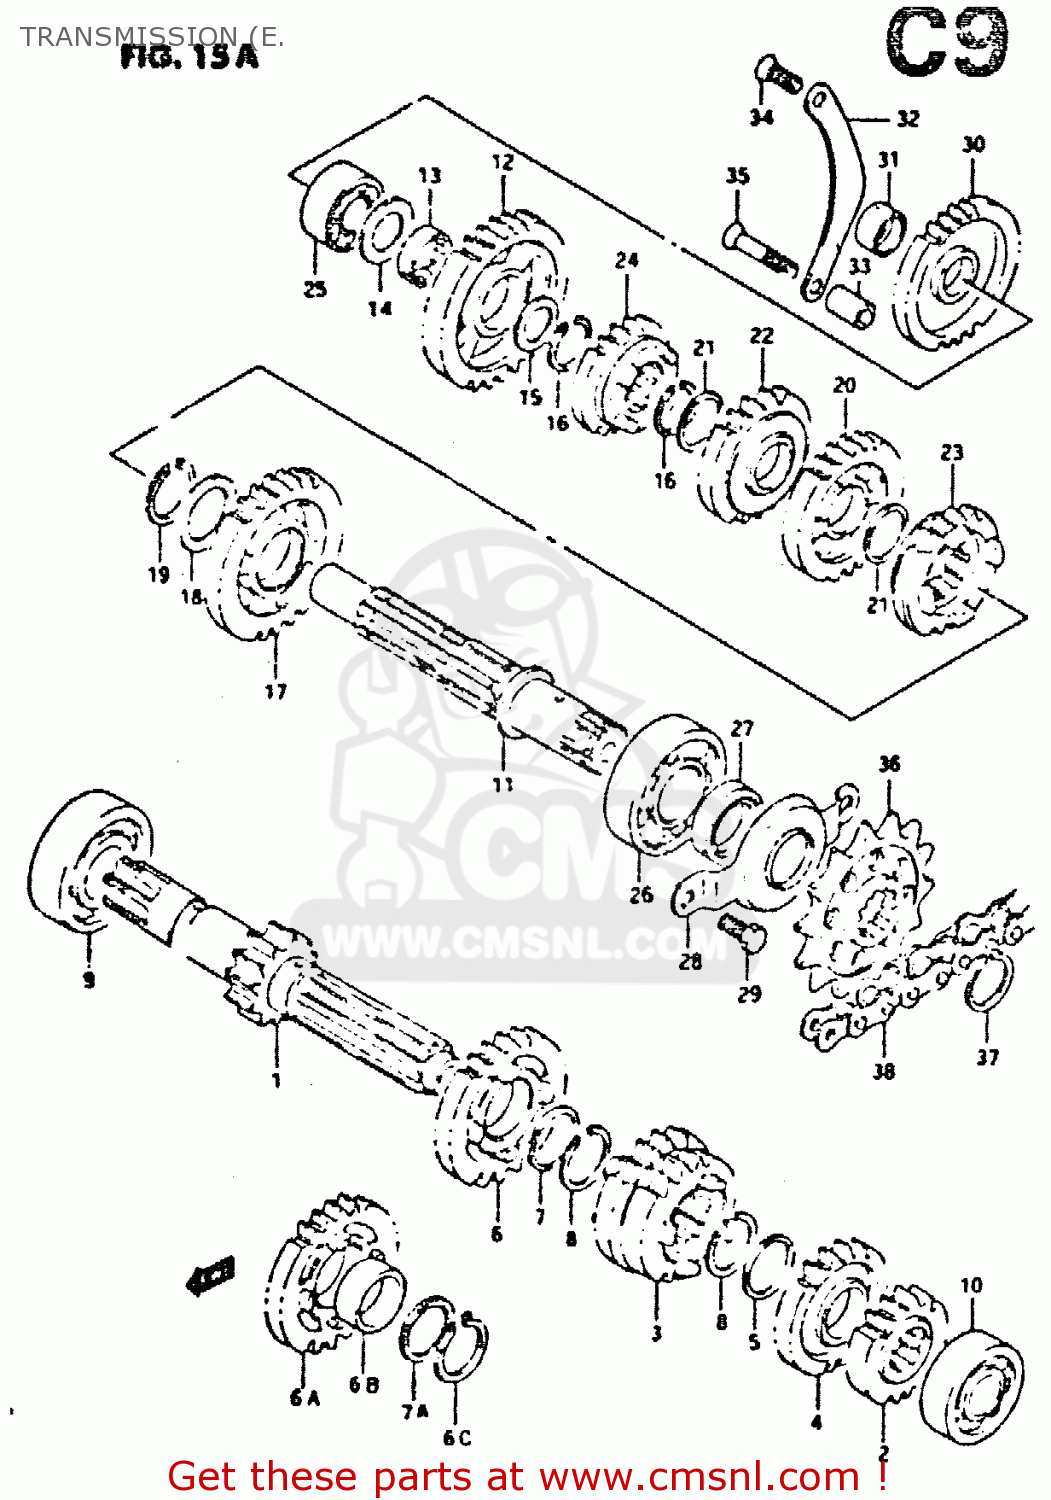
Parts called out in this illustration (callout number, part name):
1	SHAFT,COUNTER(NT:12)
2	GEAR,SECOND DRIVE (NT:15)
3	GEAR,3RD & 4TH DRIVE(NT:18/18)
4	GEAR,5TH DRIVE(NT:21)
5	WASHER
6	GEAR COMP,SIXTH DRIVE
6A	GEAR,6TH DRIVE(NT:23)
6B	BUSH(22X26X9)
6C	CIRCLIP
7	SHIM
7A	WASHER,THRUST
8	CIRCLIP
9	BEARING
10	BEARING
11	SHAFT,DRIVE
12	GEAR,1ST DRIVEN(NT:30)
13	BUSH,1ST DRIVEN GEAR
14	WASHER
15	WASHER,THRUST
16	CIRCLIP
17	GEAR,2ND DRIVEN(NT:26)
18	WASHER
19	CIRCLIP
20	GEAR,3RD DRIVEN(NT:24)
21	SHIM
22	GEAR,4TH DRIVEN(NT:20)
23	GEAR,FIFTH DRIVEN (NT:20)
24	GEAR,6TH DRIVEN(NT:19)
25	BEARING(17X40X17.5)
26	BEARING(22X56X16)
27	SEAL,OIL(22X34X7)
28	RETAINER,DRIVE SHAFT OIL SEAL
29	BOLT
30	GEAR,KICK STARTER IDLE(NT:27)
31	BUSH,KICK STARTER IDLE GEAR
32	RETAINER,KICK IDLE GEAR
33	SPACER (6.5X12X21)
34	SCREW
35	SCREW
36	SPROCKET(NT:14)
37	CIRCLIP
38	CHAIN ASSEMBLY,DRIVE
